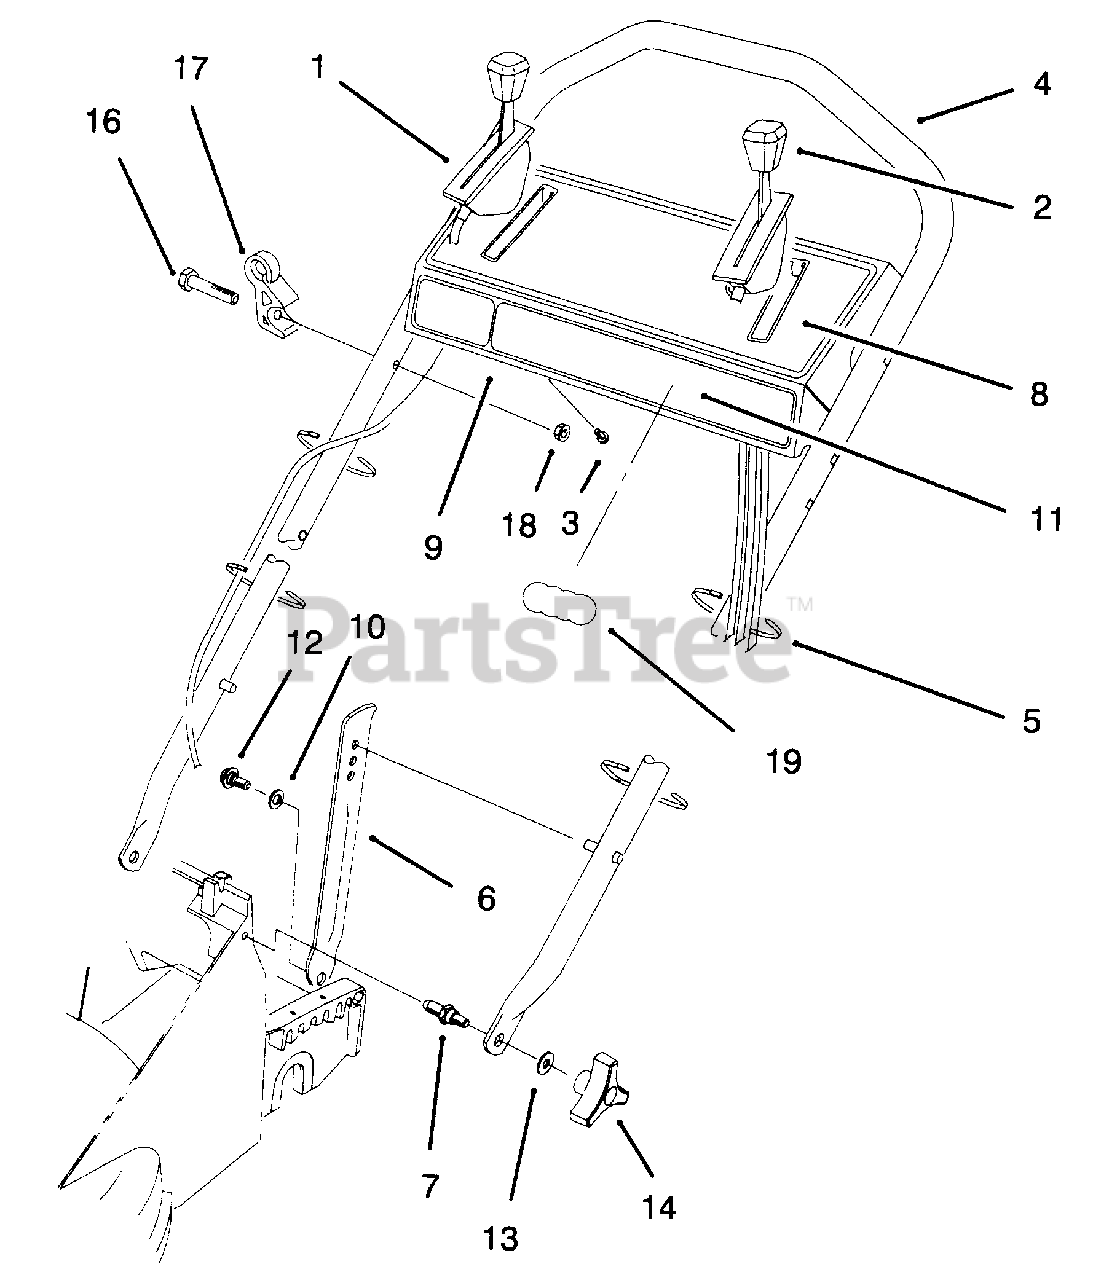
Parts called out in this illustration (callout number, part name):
1	Cable-Ground Speed
2	Cable-Throttle
3	Screw-Self Tapping
4	Handle Assembly
5	Tie-Cable
6	Latch-Handle
7	Screw-Shoulder Stud
8	Decal-Instruction
9	Panel-Control (Incl. Ref. #8)
10	Washer-Nylon
11	Decal-Panel Front
12	Bolt-Shoulder
13	Washer-Flat
14	Knob
16	Screw-Hex Hd. Cap
17	Guide-Rope
18	Nut-Lock
19	Decal-Applique
